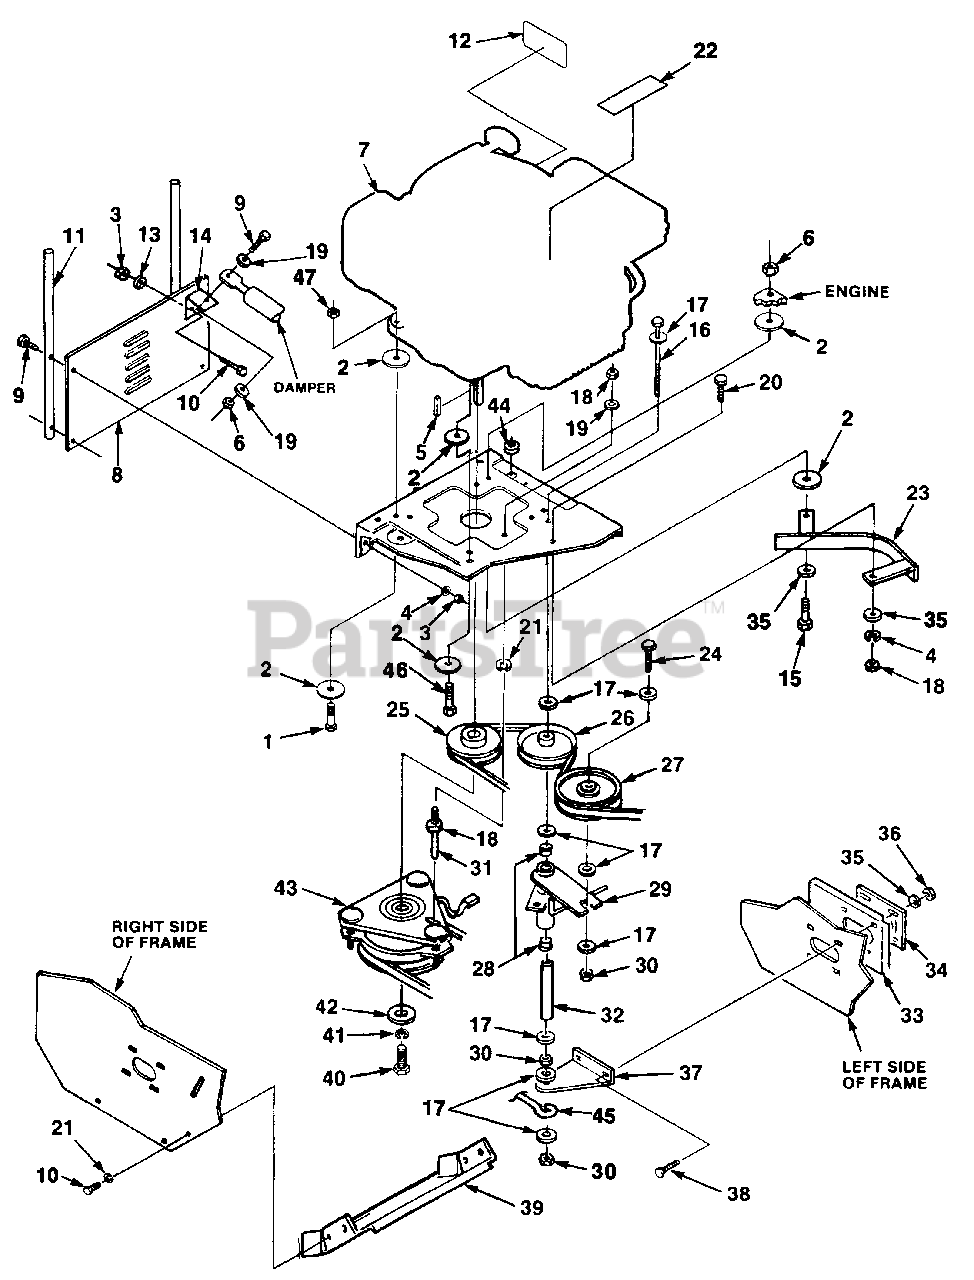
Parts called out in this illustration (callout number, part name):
1	SCREW- m8 x 1.25 x 40mm
2	WASHER- 5/16
3	NUT- 1/4-20 hex
4	WASHER- 1/4
5	KEY- 1/4 x 1/4 x 1
6	NUT- Lock 5/16 x 18
8	PANEL- Rear
9	BOLT- 5/16-18 x 3/4
10	SCREW- 1/4-20 x 5/8
11	TUBE- Catcher Stand
12	DECAL- Warning
13	WASHER 1/4
14	BRACKET- Damper
15	BOLT- 5/16-18 x 1 3/4
16	BOLT- 3/8-16 x 5 1/2
17	WASHER- 3/8 flat
18	NUT- Hex 5/16-18
19	WASHER- Flat 5/16
20	SCREW- 1/4-20 x .750
21	WASHER- Lock 5/16
22	DECAL- Warning
23	GUIDE- Belt
24	SCREW- 3/8-16 x 1 3/4
25	PULLEY- Engine
26	PULLEY- Idler
27	PULLEY- Idler
28	BEARING- Flange
29	ARM- Pivot
30	NUT- Hex Centerlock 3/8-16
31	PIN- Clutch torque
33	SUPPORT- Frame
34	RETAINER & BEARING
35	WASHER- Flat 1/4
36	NUT- Centerlock hex 1/4-20
38	BOLT- Rd. hd. carr. 1/4-20 x .750
39	PAN-Bottom
40	BOLT- Hex hd. 7/16-20 x 2 3/4
41	WASHER- Lock Heavy 7/16
42	CLUTCH- Retainer
43	CLUTCH- Warner Brake
45	GUIDE BELT- Wireform
